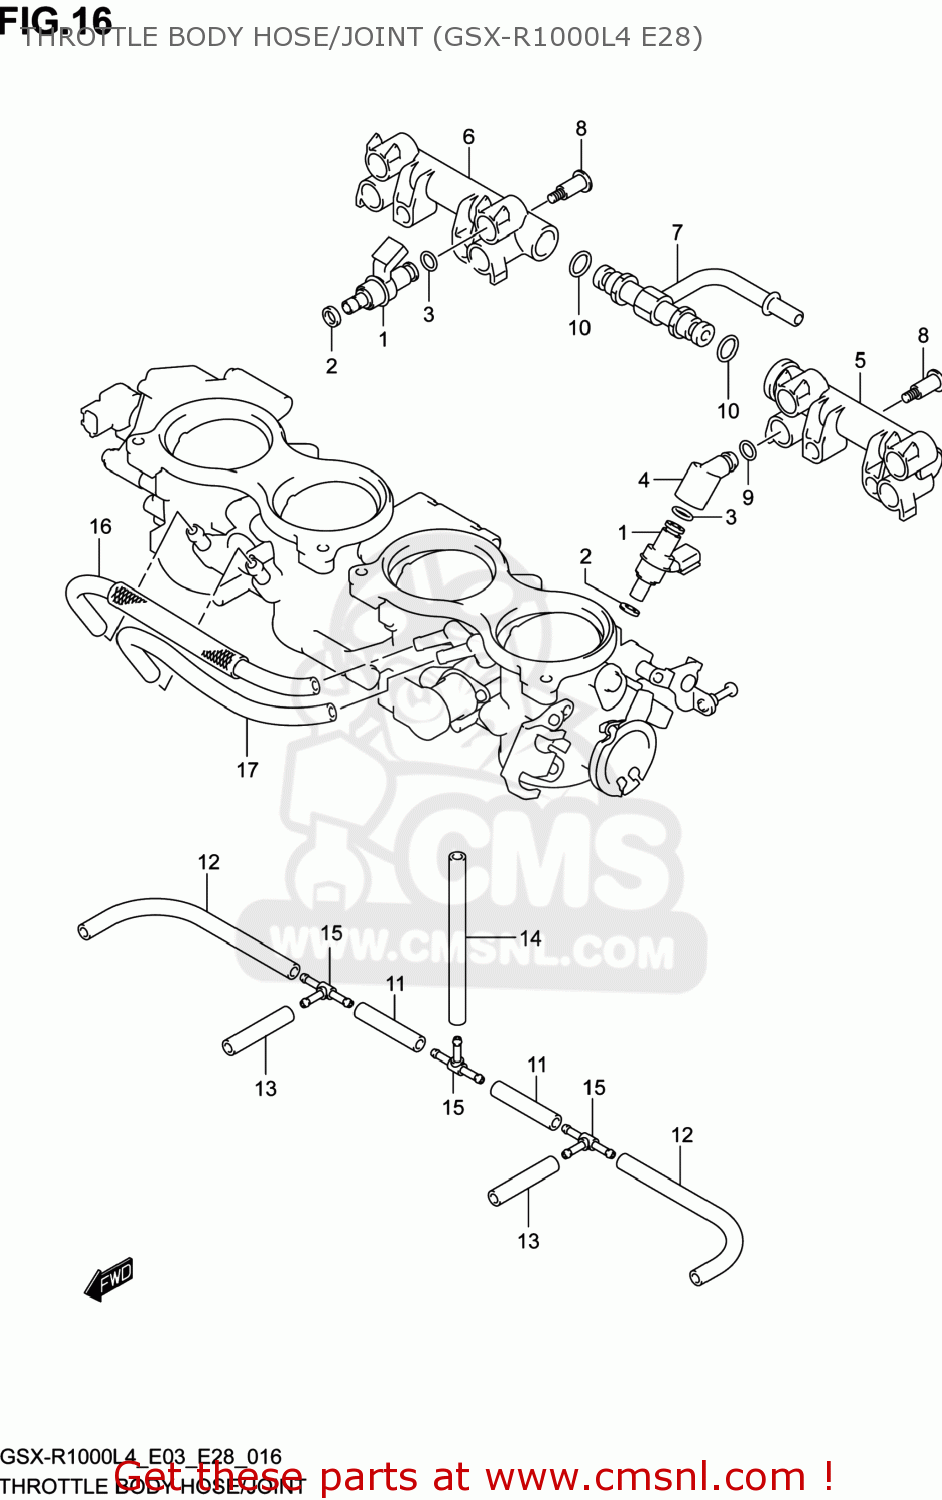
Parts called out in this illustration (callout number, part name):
1	INJECTOR ASSY
2	RING,SEAL
3	O RING
4	PIPE,FUEL
5	PIPE,FUEL
6	PIPE,FUEL
7	JOINT
8	SCREW
9	O RING
10	O RING
11	HOSE
12	HOSE
13	HOSE
14	HOSE
15	JOINT
16	TUBE
17	TUBE
